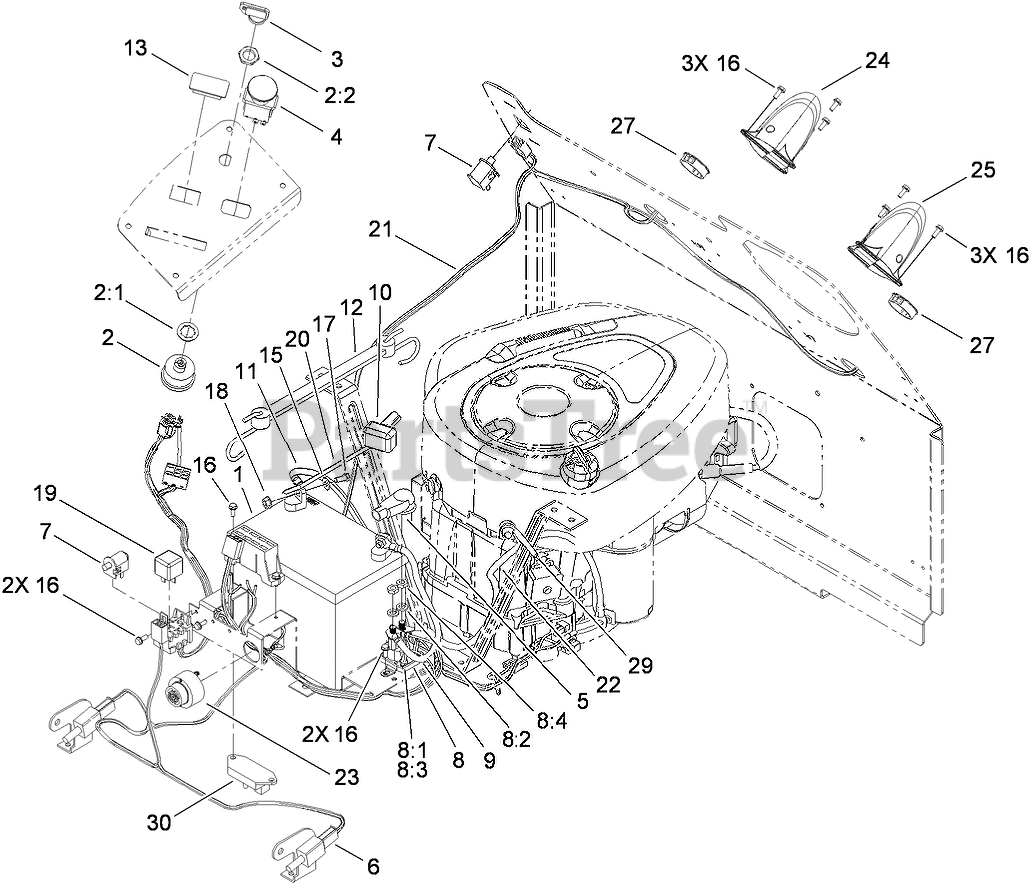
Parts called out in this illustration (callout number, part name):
1	BATTERY
2	Key Switch ASM
2:1	WASHER-TOOTH, INTERNAL
2:2	NUT-HH
3	KEY-IGNITION
4	SWITCH-PTO
5	BOOT-TERMINAL
6	SWITCH
7	SWITCH-BAIL
8	SWITCH-SOLENOID
8:1	WASHER-LOCK
8:2	WASHER-LOCK
8:3	NUT-HEX
8:4	NUT-JAM
9	CABLE-BATTERY, POSITIVE
10	BOOT-INSULATOR, TERMINAL
11	CABLE-NEGATIVE, BLACK
12	HOLDDOWN-BATTERY
13	PLUG-HOLE
15	WASHER-FLAT
16	SCREW-TAPTITE
17	SCREW-HH
18	NUT-HF
19	RELAY
20	TIE-CABLE
21	HARNESS-WIRE
22	WIRE-21 INCH
23	ALARM-TONE, DUAL
24	BAG SENSOR ASM
25	BAG SENSOR ASM
27	BUSHING-HARNESS, WIRE
29	CLAMP-HOSE
30	MODULE-DELAY
